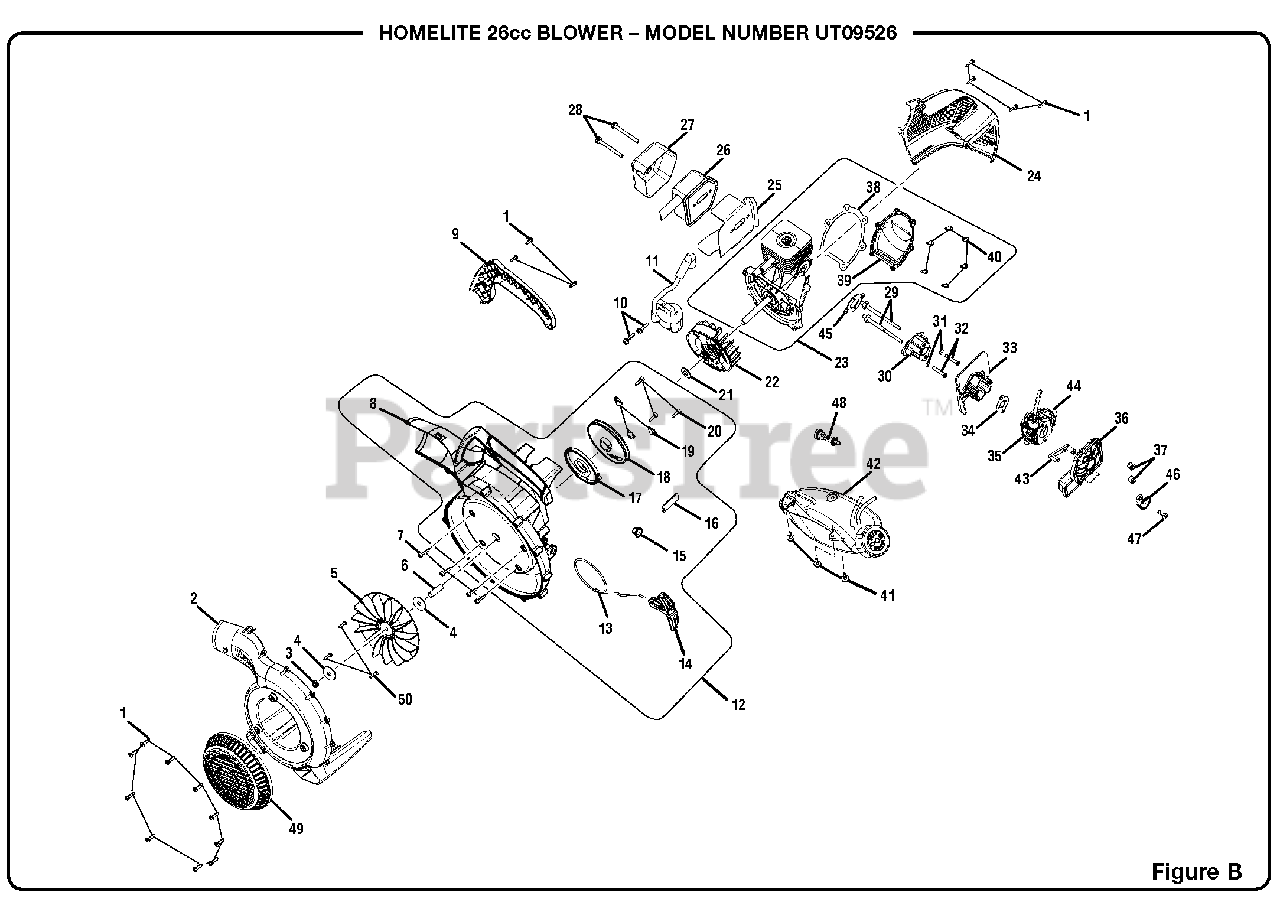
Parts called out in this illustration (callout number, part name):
1	Screw (M4 x 18 mm, T20 Torx Hd)
2	Outer Volute
3	Lock Nut (3/8 in)
5	Fan
7	Screw (M4 x 17 mm,T20 Torx Hd TF)
8	Inner Volute
9	Handle Cover
10	Screw (M4 x 19 mm, T20 Torx Pan Hd TF)
11	Ignition Module
12	Lower Housing w/Starter Assembly
13	Starter Rope (42 in)
14	Starter Grip
17	Spring & Container
18	Starter Pulley
19	Pulley Retainer
20	Screw (M4 x 14 mm, T20 Torx Hd TF)
22	Rotor and Pawl Assembly
23	Short Block Assembly
24	Engine Cover w/Heat Shield
25	Muffler Gasket
26	Muffler Assembly
27	Muffler Heat Shield
28	Bolt (10-24 x 2-1/8 in)
29	Bolt (M5 x 62 mm)
32	Screw (M5 x 25 mm, T20 Torx Hd)
34	Heat Dam Gasket
35	Carburetor
36	Air Box Base
37	Hex Nut (M5)
38	Crankcase Cover Gasket
39	Crankcase Cover
40	Screw (M4 x 12 mm, T20 Torx Hd)
41	Screw (M4 x 14 mm, T25 Torx Truss Hd)
42	Fuel Tank Assembly w/Cap
43	Choke Lever
44	Primer Bulb
45	Heat Dam Gasket
46	Choke Cover
47	Screw (M4 x 12 mm, T20 Torx Pan Hd)
48	Fuel Filter
49	Blower Door
50	Screws (10-14 x 3/4 in, T25 Torx Pan Hd TF)
